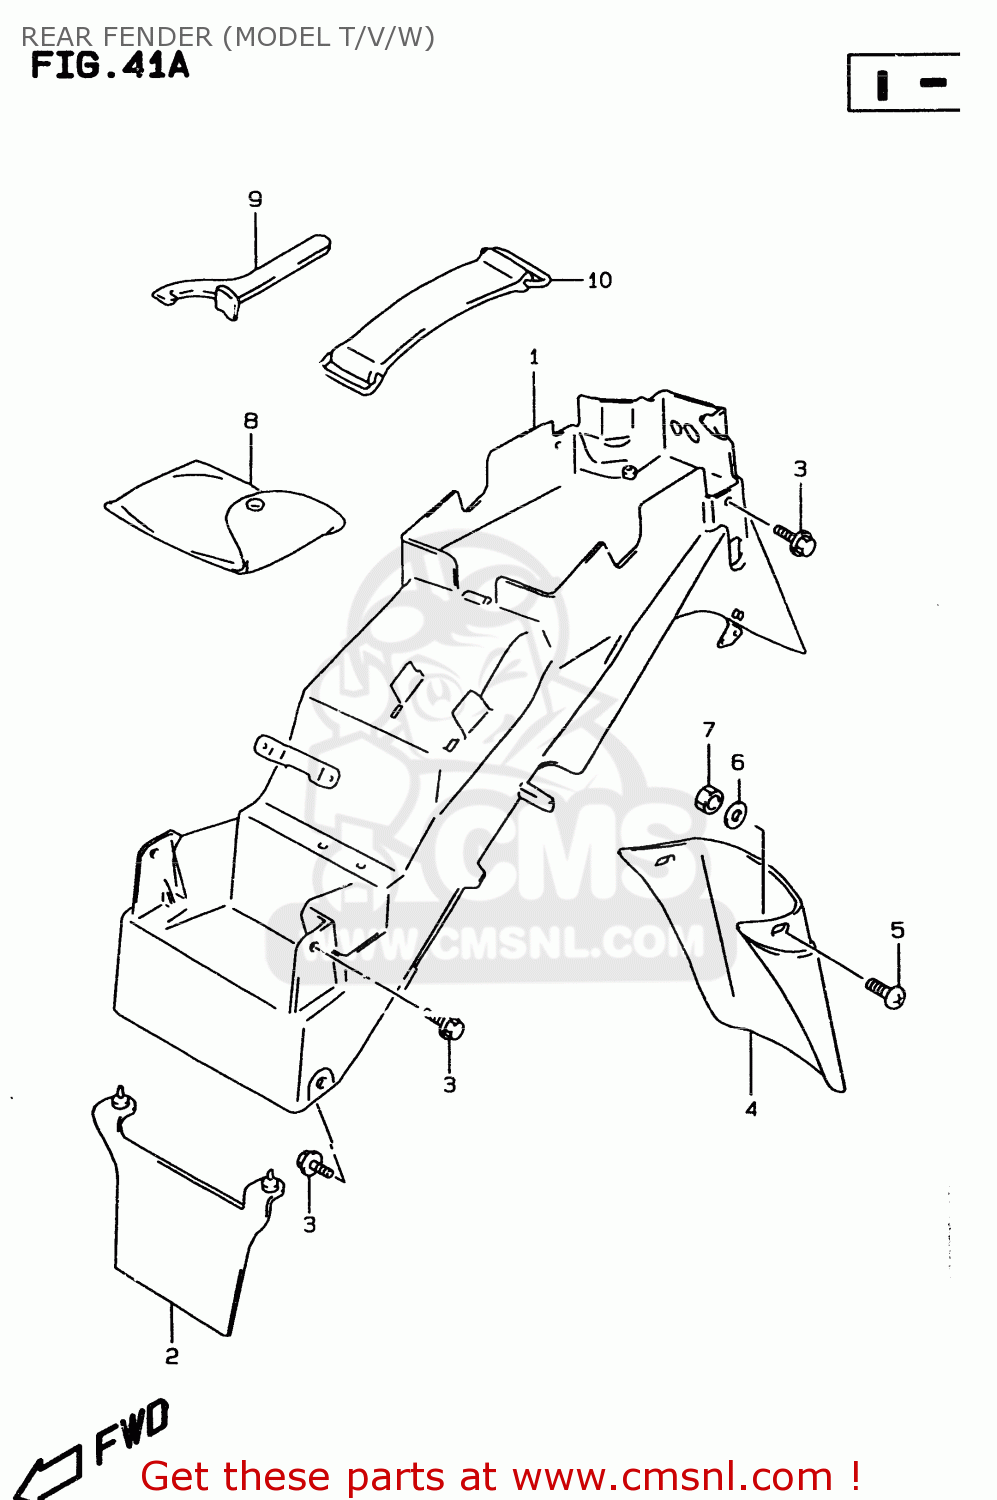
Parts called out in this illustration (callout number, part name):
1	FENDER, REAR
2	MUDGUARD,RR FENDER FR
3	BOLT(6X16)
4	EXTENSION,RR FENDER
5	SCREW
6	WASHER(6.5X18X1.6)
7	NUT 6MM
8	TOOL ASSY
9	CLAMP
10	BAND
